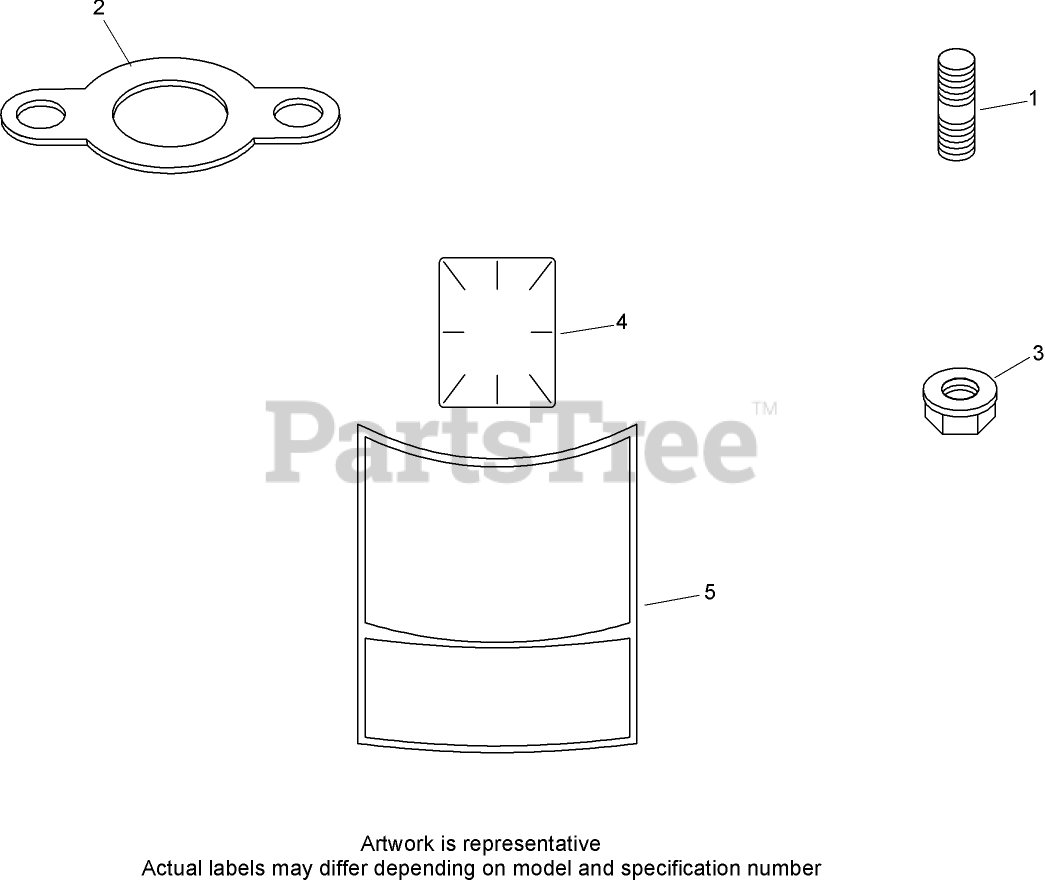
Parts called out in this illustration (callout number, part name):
1	STUD (M8X1.25X33)
2	Gasket-Exhaust
3	NUT-FLANGE (M8X1.25)
4	DECAL-LAMINATE, CLEAR
5	DECAL (19 H P)
